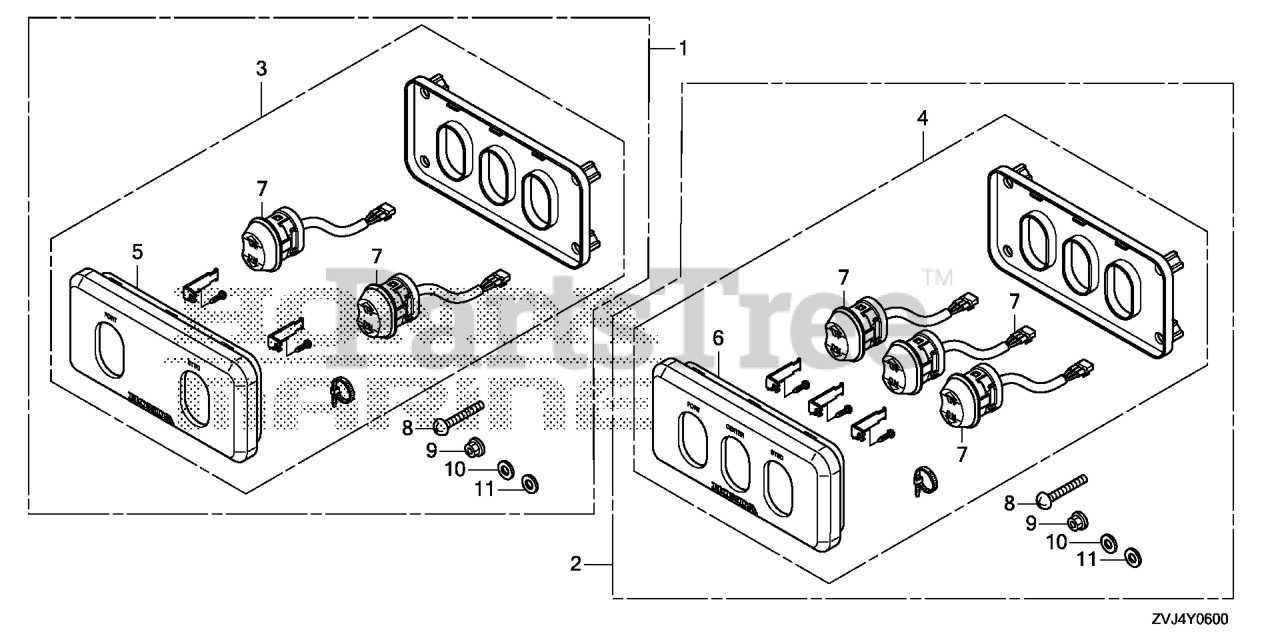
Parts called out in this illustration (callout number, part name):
1	PANEL KIT, POWER TRIM-TILT SWITCH (TWIN)
2	PANEL KIT, PTT SW
3	PANEL ASSY., POWER TRIM-TILT SWITCH (TWIN)
4	PANEL ASSY., POWER TRIM-TILT SWITCH (TRIPLE)
5	PANEL, POWER TRIM-TILT SWITCH (TWIN)
6	PANEL, POWER TRIM-TILT SWITCH (TRIPLE)
7	SWITCH ASSY., POWER TILT
8	SCREW, PAN (5X40) DUAL QTY = (8) (SINGLE)
9	NUT, FLANGE (5MM)
10	WASHER, PLAIN (5MM)
11	WASHER, SPRING (5MM)
11	WASHER, SPG (5MM)
